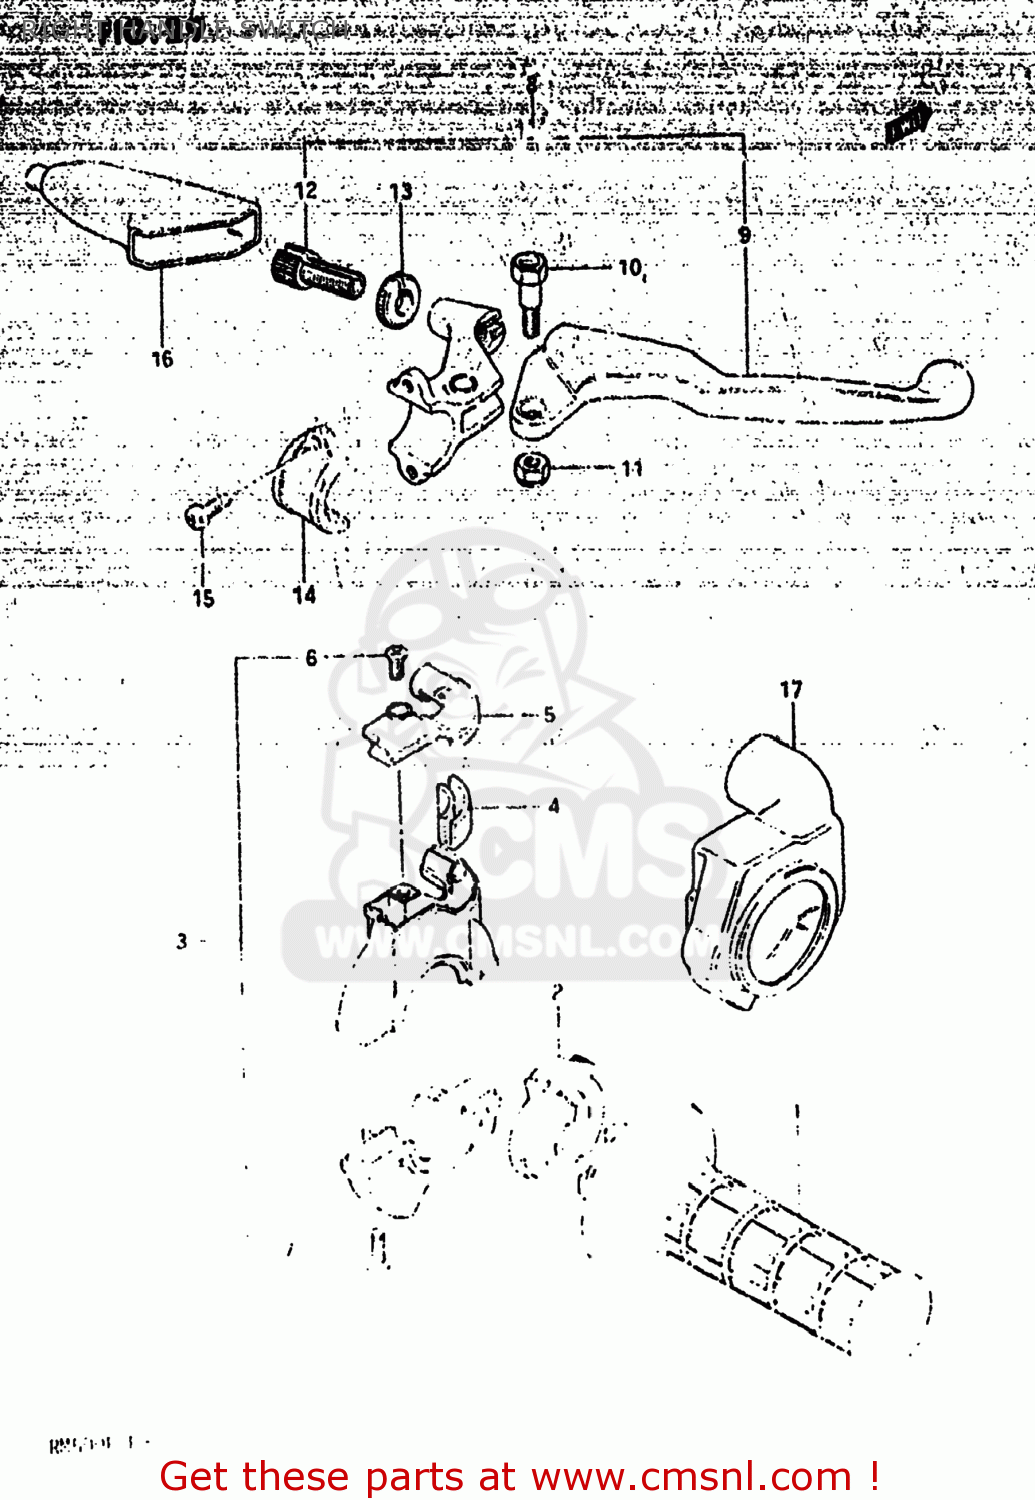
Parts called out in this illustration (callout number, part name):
1	GRIP,THROTTLE
2	ROTOR,THROTTLE GRIP
3	CASE ASSY,THROTTLE
4	GUIDE PIECE,THROTTLE
5	COVER,THROTTLE CASE
6	SCREW
7	SCREW
8	LEVER ASSEMBLY,BRAKE
9	LEVER,BRAKE
10	BOLT,LEVER
11	NUT 6MM
12	ADJUSTER,CABLE
13	NUT,CABLE ADJUSTER
14	BRACKET,CLUTCH LEVER HOLDER
15	SCREW
16	COVER,CLUTCH LEVER
17	COVER,THROTTLE CASE
